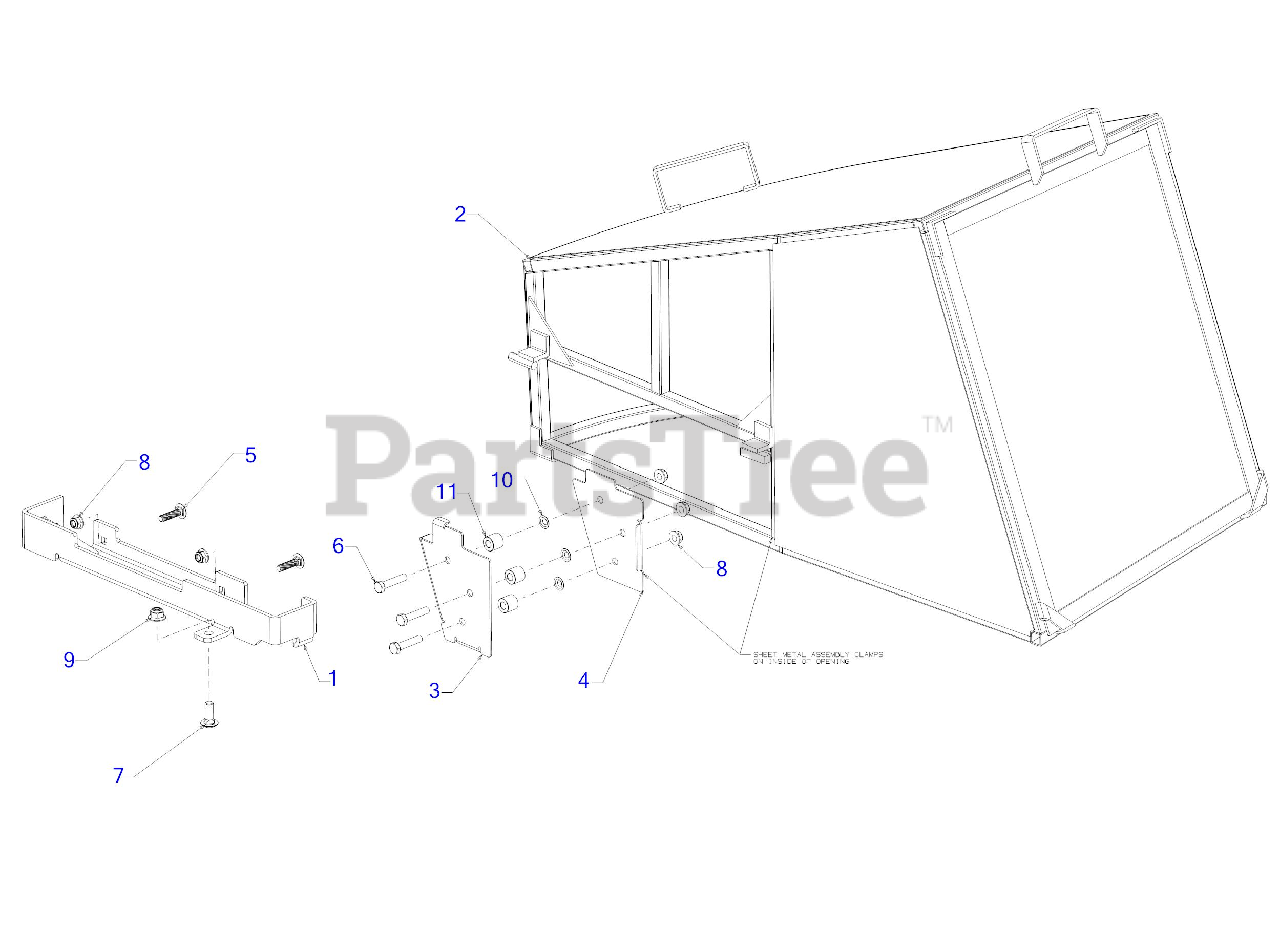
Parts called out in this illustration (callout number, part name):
5	CARRIAGE BOLT 5/16-18 X 1.25
6	SCREW 5/16-18 x 1.5 LG
7	CARRIAGE BOLT 3/8-16 x 1.00 GR5
8	FLANGE LOCK NUT 5/16-18
11	SPACER .34 x .75 x .63 LG
